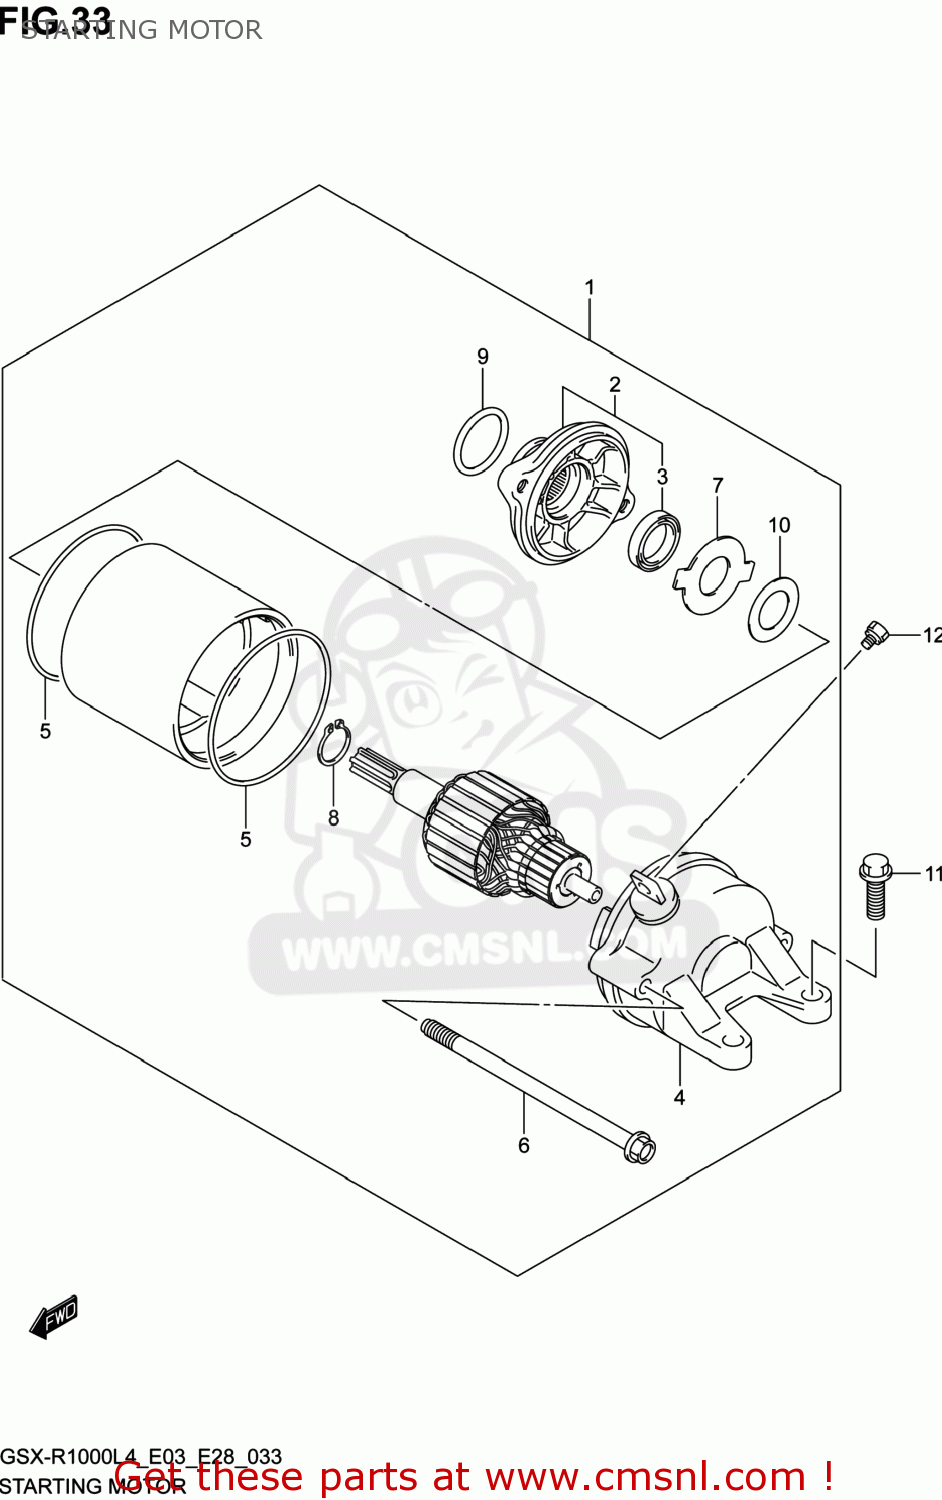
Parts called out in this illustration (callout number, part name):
1	MOTOR ASSY,STARTING
2	HOUSING ASSY
3	SEAL,OIL
4	FRAME ASSY
5	O RING
6	BOLT
7	PLATE,LOCK
8	RING,SNAP
9	O RING(COLLAR:BROWN)
10	SHIM
11	BOLT(6X20)
12	SCREW(5X8)
